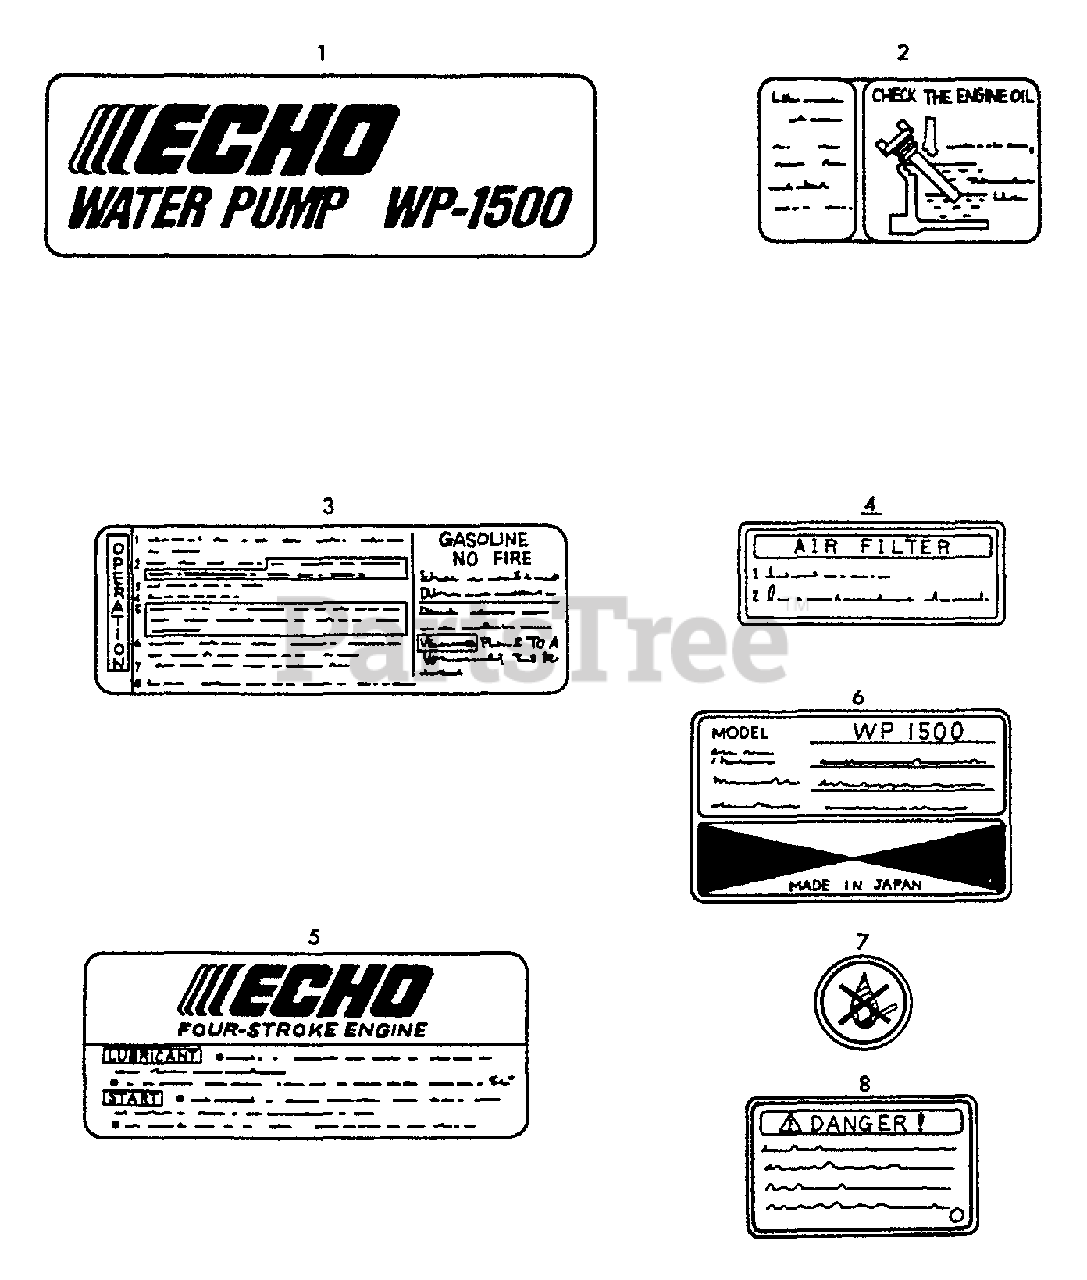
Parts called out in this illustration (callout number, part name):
1	LABEL - MODEL WP1500
2	LABEL, OIL
3	LABEL - CAUTION -- OPERATION
4	LABEL - AIR FILTER
5	LABEL - ECHO
6	LABEL, ENGINE NAME
7	LABEL, NON FIRE
8	LABEL, DANGER
